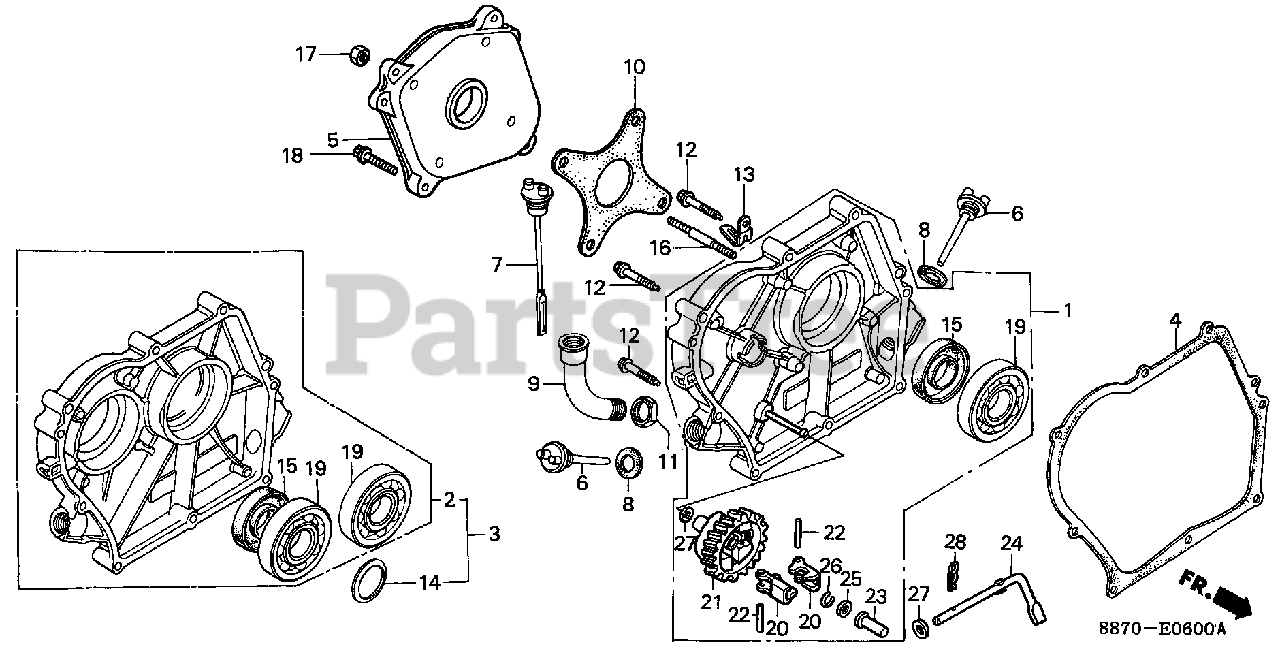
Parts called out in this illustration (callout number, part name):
1	COVER ASSY., CRANKCASE
4	GASKET, CASE COVER
6	CAP, OIL (YELLOW)
8	GASKET, OIL FILLER CAP
12	BOLT, FLANGE (6X32)
15	OIL SEAL (25X41X6)
19	BEARING, RADIAL BALL (6205)
